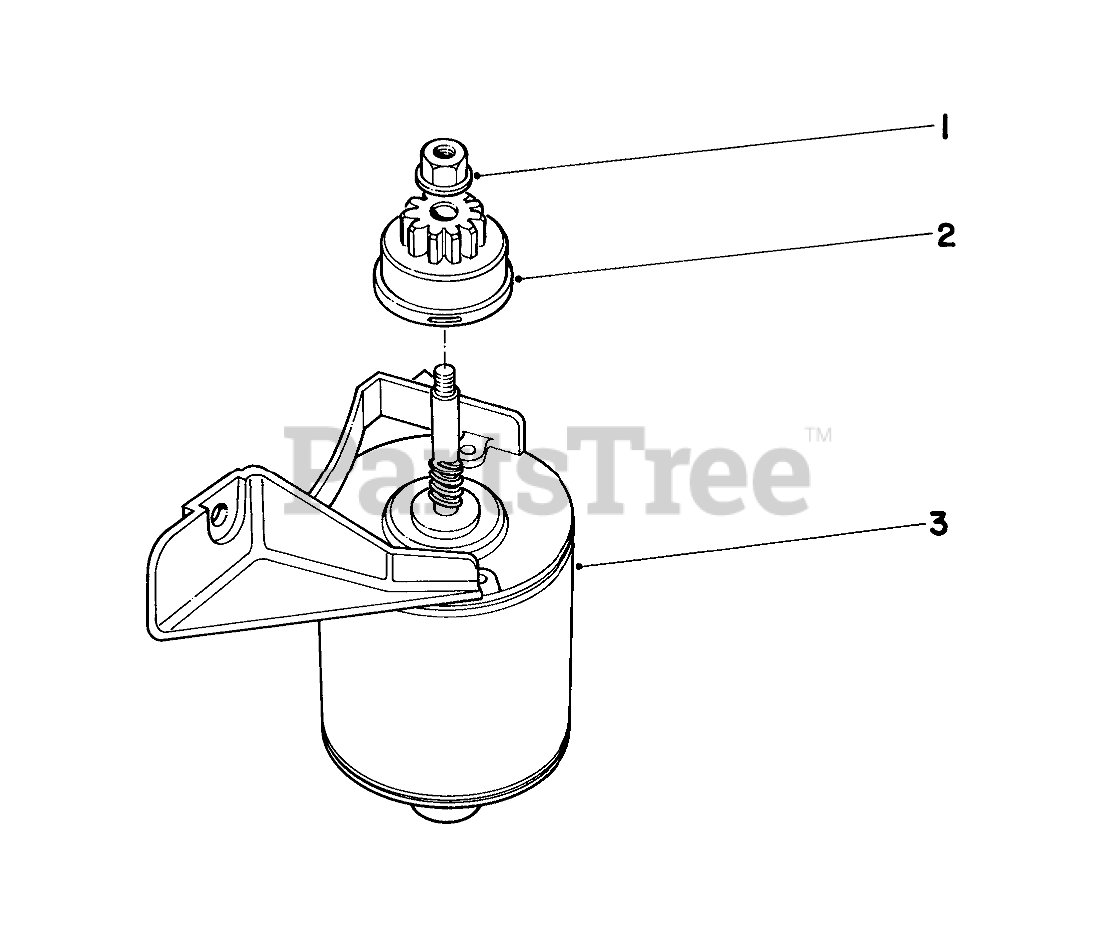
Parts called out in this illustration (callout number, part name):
1	Flange Nut
2	PINION ASM 12 TOOTH
3	Starter Motor
